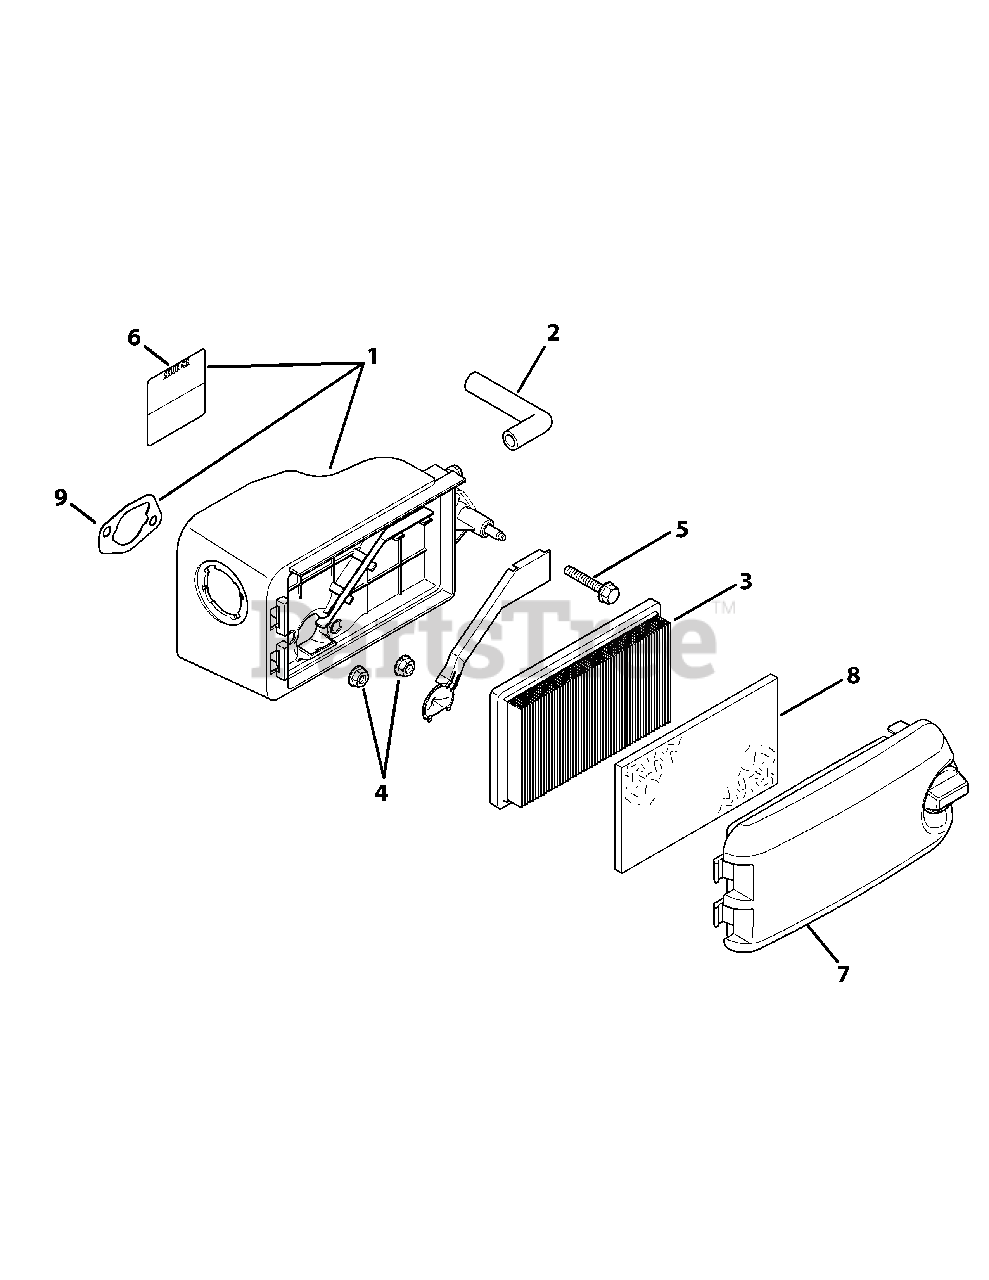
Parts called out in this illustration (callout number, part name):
1	Air Cleaner Base Kit
2	Breather Hose
3	Air Cleaner Element, Filter
4	Hex Flange Nut, M6
5	Hex Flange Screw, M6
6	Service Nameplate
7	Air Cleaner Cover
8	Carbon Pre-Filter Element
9	Intake Gasket Kit
